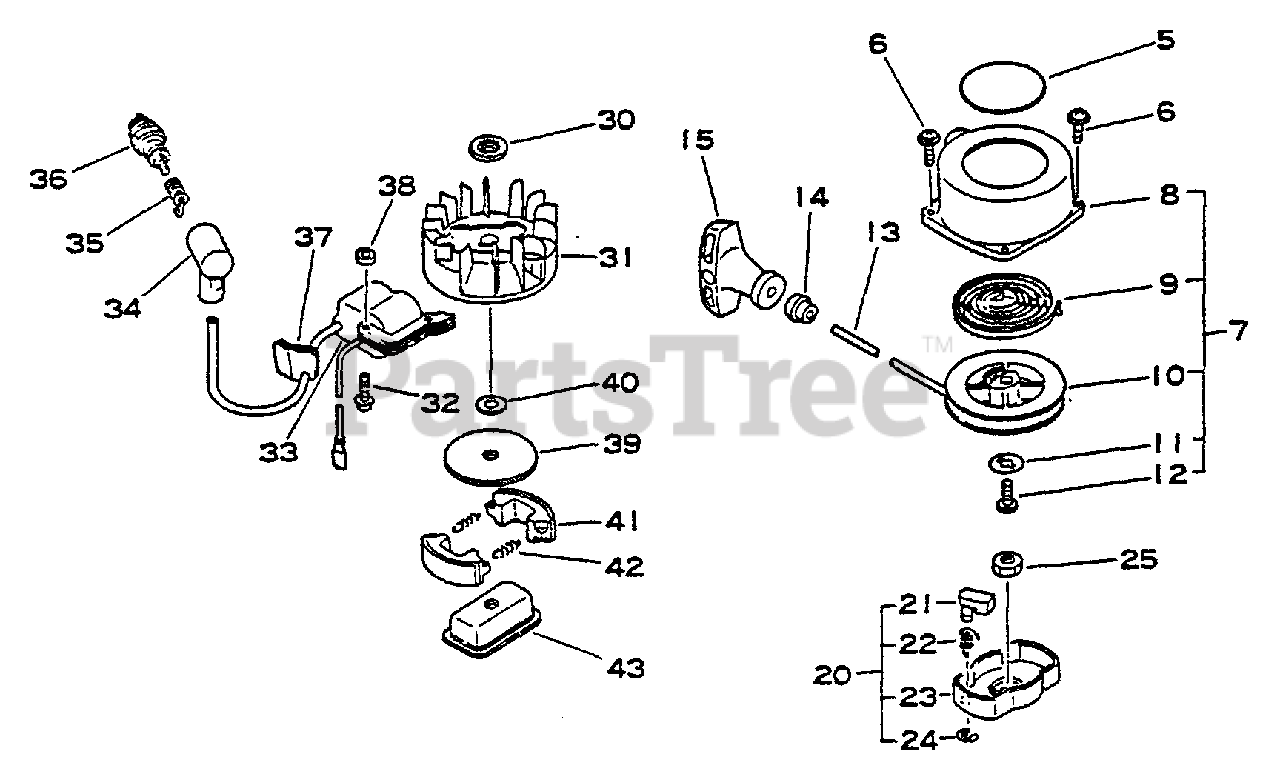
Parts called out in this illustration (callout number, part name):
5	LABEL - ECHO
6	SCREW - 4X14
7	STARTER ASSY
8	CASE, STARTER
9	SPRING, REWIND
10	REEL, ROPE
11	WASHER
13	ROPE, STARTER - 3X890
14	GUIDE, ROPE
15	GRIP, STARTER
20	STARTER PAWL ASSY
21	PAWL, STARTER
22	SPRING, RETURN
23	CATCHER, PAWL
24	RING, RETAINING - 6
30	WASHER
31	FLYWHEEL
32	SCREW - 4X22
33	COIL, IGNITION
34	CAP, SPARK PLUG
35	TERMINAL, SPARK PLUG CAP
36	SPARK PLUG -- BM-6A
37	COVER, DUST
39	PLATE, CLUTCH
41	SHOE, CLUTCH
42	SPRING, CLUTCH
43	HUB, CLUTCH
